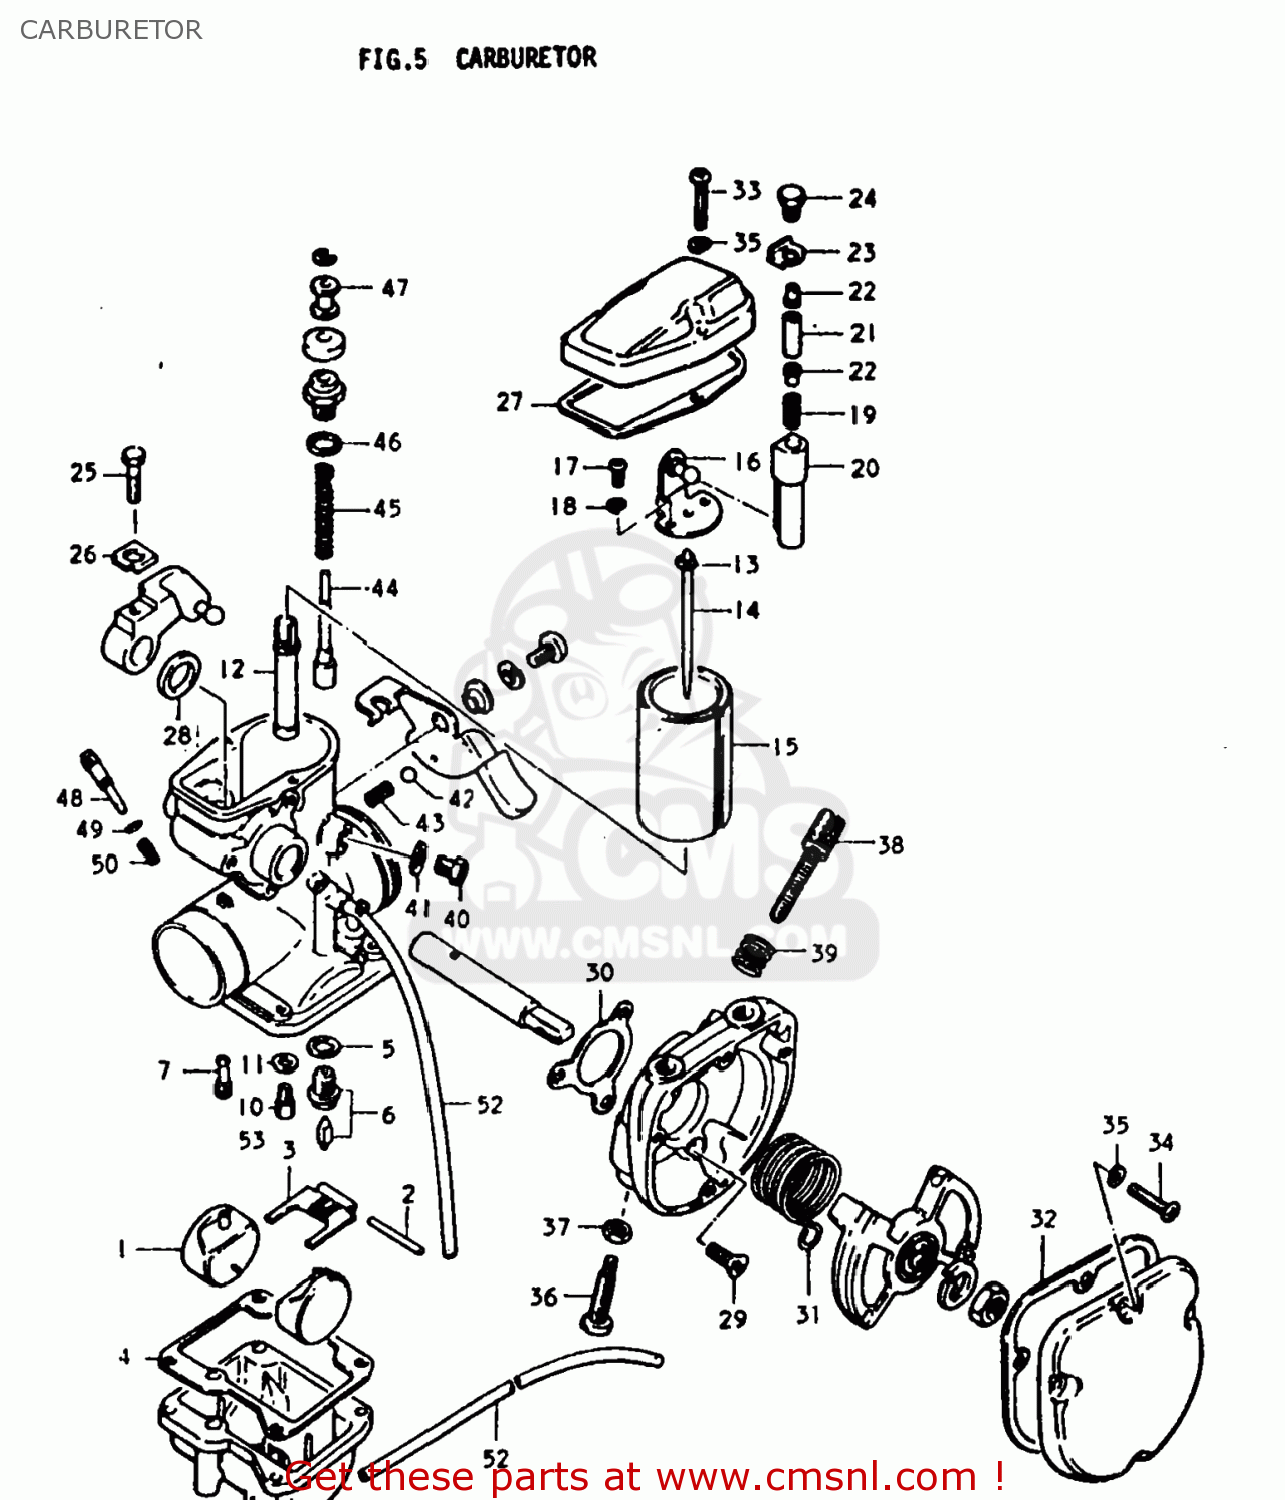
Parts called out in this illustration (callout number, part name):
1	FLOAT
2	PIN,FLOAT
3	GASKET,FLOAT CAHMBER (NAS)
4	GASKET,VALVE SEAT (NAS)
5	VALVE ASSY,NEEDLE
6	JET,PILOT(25)
7	PLUG
8	GASKET,DRAIN PLUG (MCA)
9	JET,MAIN(140)
10	WASHER
11	JET,NEEDLE
12	VALVE,THROTTLE
13	NEEDLE JET
14	CLIP
15	PLATE,THROTTLE VALVE
16	SCREW
17	LOCK WASHER
18	RING
19	WASHER,JET NEEDLE
20	BRACKET,CARBURETOR
21	SPRING
22	ADJUSTER
23	SPRING
24	O RING
25	SPRING
26	LEVER ASSEMBLY
27	SPRING
28	PIN,CARBURETOR
29	SCREW
30	PLATE,CARBURETOR
31	BOLT
32	RING
33	GASKET,TOP (NAS)
34	RING
35	GASKET,CARBURETOR CASE
36	SCREW(5X12)
37	SPRING
38	GASKET,CARBURETOR CASE
39	SCREW
40	LOCK WASHER
41	SCREW 4X25
42	LOCK WASHER
43	SCREW
44	LOCK WASHER
45	SCREW
46	NUT 6MM
47	SCREW,THROTTLE STOP
48	SPRING,THROTTLE SCREW
49	GASKET,THRO VALVE INSPECTION (NAS)
50	BOLT
51	BALL,STARTER SHAFT
52	SPRING,STARTER SHAFT
53	SCREW,PILOT AIR
54	O RING
55	SPRING
56	VALVE,STARTER
57	SPRING
58	O-RING
59	RING
60	HOSE
